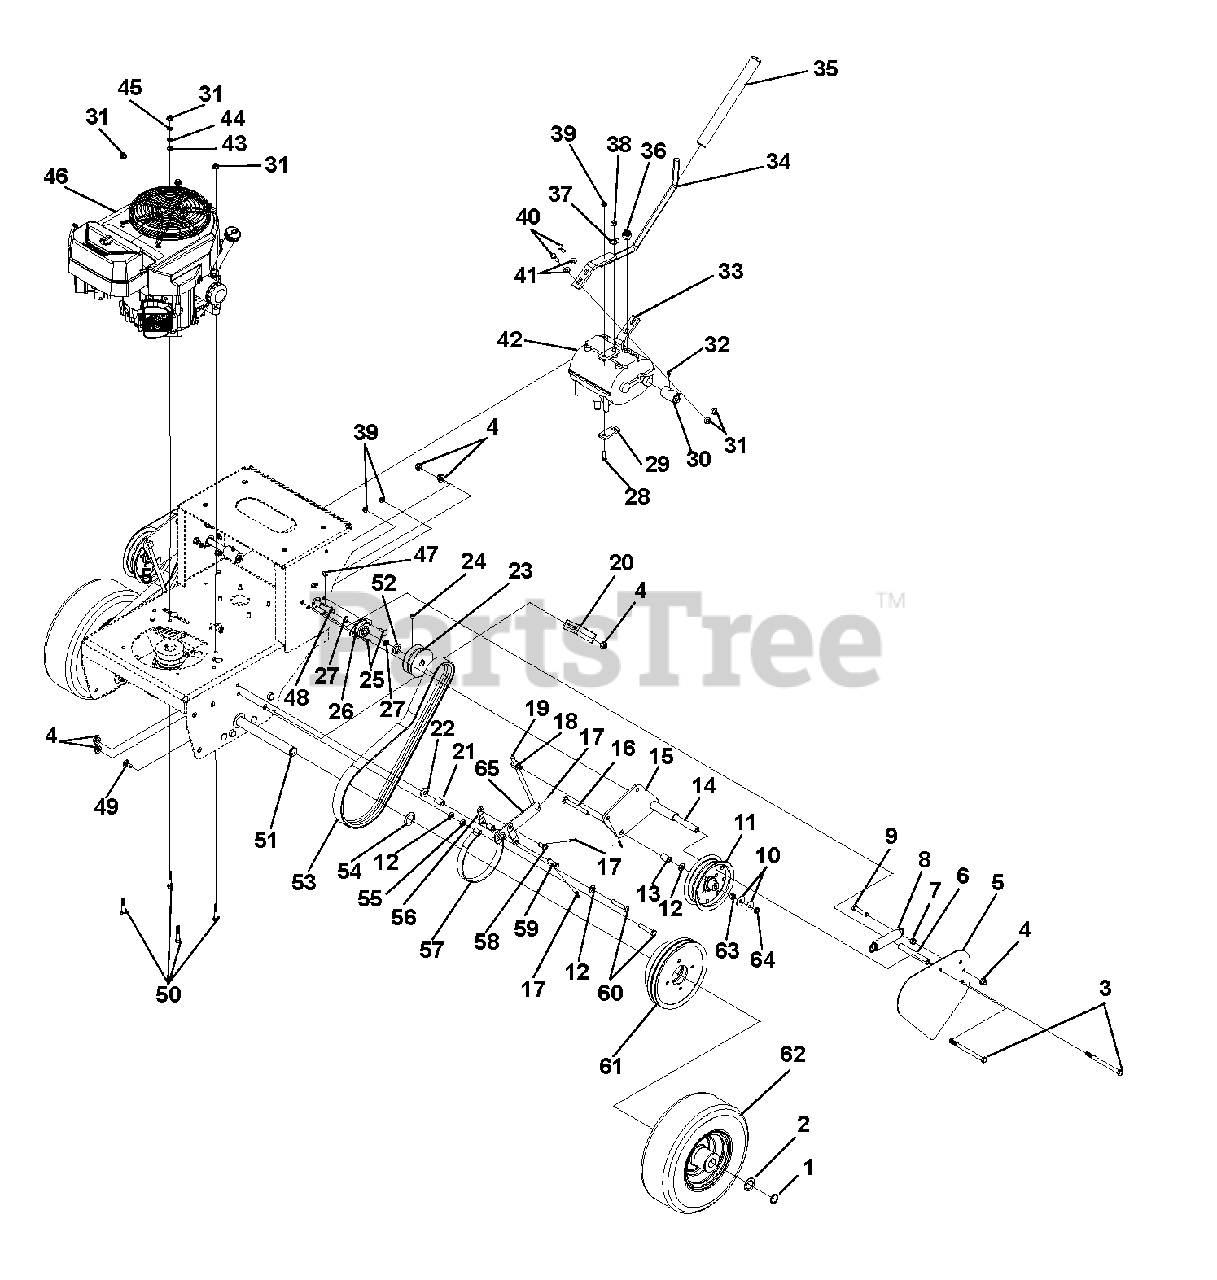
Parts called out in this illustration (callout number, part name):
1	Ring-Retaining-External 1.00 x .078
2	Washer, Flat-Steel 1.010 x 1.505 x .062
3	Bolt, .38-16 x5.00 Hex 5
4	Nut, .38-16 Nyloc Flange
5	Cover, Traction Belt
6	Bushing,S.385 x .610 x 4.32 Steel
7	Nut, .38-16 Standard Hex Grade 5
8	Spring-Tension .105 x 1.00 x 5.0
9	Bolt, .38-16 x 1.75 Hex 5
10	Washer, Flat Steel .375X1.125X.065
11	Pulley, Flat 5.0 x .38 w/BRG
12	Washer, .406 x .813 x .065 Flat
13	Bushing, Sleeve .375 x .625 x .1.000
14	Bushing, S.385 x .610 x 4.32 Steel
15	Weldment, Wheel Clutching Arm-Left Hand
16	Bolt, Round Head Square Neck .38-16 x 3.5 Grade 5
17	Pin, Hair
18	Swivel, .38-24
19	Rod, Brake Actuating
20	Plate, Belt Finger
21	Bushing, S.391 x .622 x .95 St
22	Washer, Flat Steel .406 x 1.00 x .188
23	Sheave, Drive 3.25 OD x .625 ID
24	Screw, Set .31-18X.38 Socket Head
25	Bolt, .25-20 x .750 Crg 5
26	Bearing, Flange .625 x 1.875 x .797
27	Ring, Retaining-External .579 x .035
28	Bolt, .25-20 x 1.00 Hex 5
29	Plate, Shift
31	Nut, .31-18 Nyloc Flange
32	Fitting, .25-28 STRGT Grease Zerk
33	Bracket, Shift Lever
34	Welment, Shift Lever
35	Grip, Handlebar
36	Switch, Nuetral Start (N.O.)
37	Washer, Locking .375 x .130
38	Nut, Locking-Center .375-24
39	Nut, .25-20 Nyloc Flange
40	Bolt, .3125-18 x 3.25 Hex 5
41	Washer, Flat Steel .344 x .688 x .065
42	Transmission
43	Washer, .313 Medium Spring Lock
44	Nut, Locking-Center Jam .31-18
45	Washer, Locking-EXT .326 x .599 x .031
46	Engine, KAWI FH381V KAI 13HP (143, 144)
47	Key, Woodruff .19 x .75 HRD#9
48	Shaft, Half
49	Bolt, .38-16 x .750 CRG 5 LN
50	Bolt, .3125-18 x 1.75 Hex 5
51	Shaft, Axle
52	Washer, Flat .765 x 1.125 x .187
53	Belt, Gear Drive 49" Elbow COG
54	Washer, Hard-Thrust 1.007 x 1.542 x .062
55	Nut, .38-16 Standard Hex Grade 5
56	Link, Brake Arm
57	Assembly, Brake Band, Pro
58	Pin, CVS .375 x .750 x .516
59	Pin, Clevis .38 x 1.25
60	Bolt, .38-16 x 2.00 Hex 5
61	Assembly, Pulley and Drum
62	Assembly, Wheel And Tire 6 x 3.5 (143)
63	Locknut, .38-16 Center
64	Nut, Locking-Jam-Center .375-16
65	Weldment, Brake Actuating Lever
NS	Air Filter
NS	Oil Filter
NS	Fuel Filter
NS	Spark Plug
